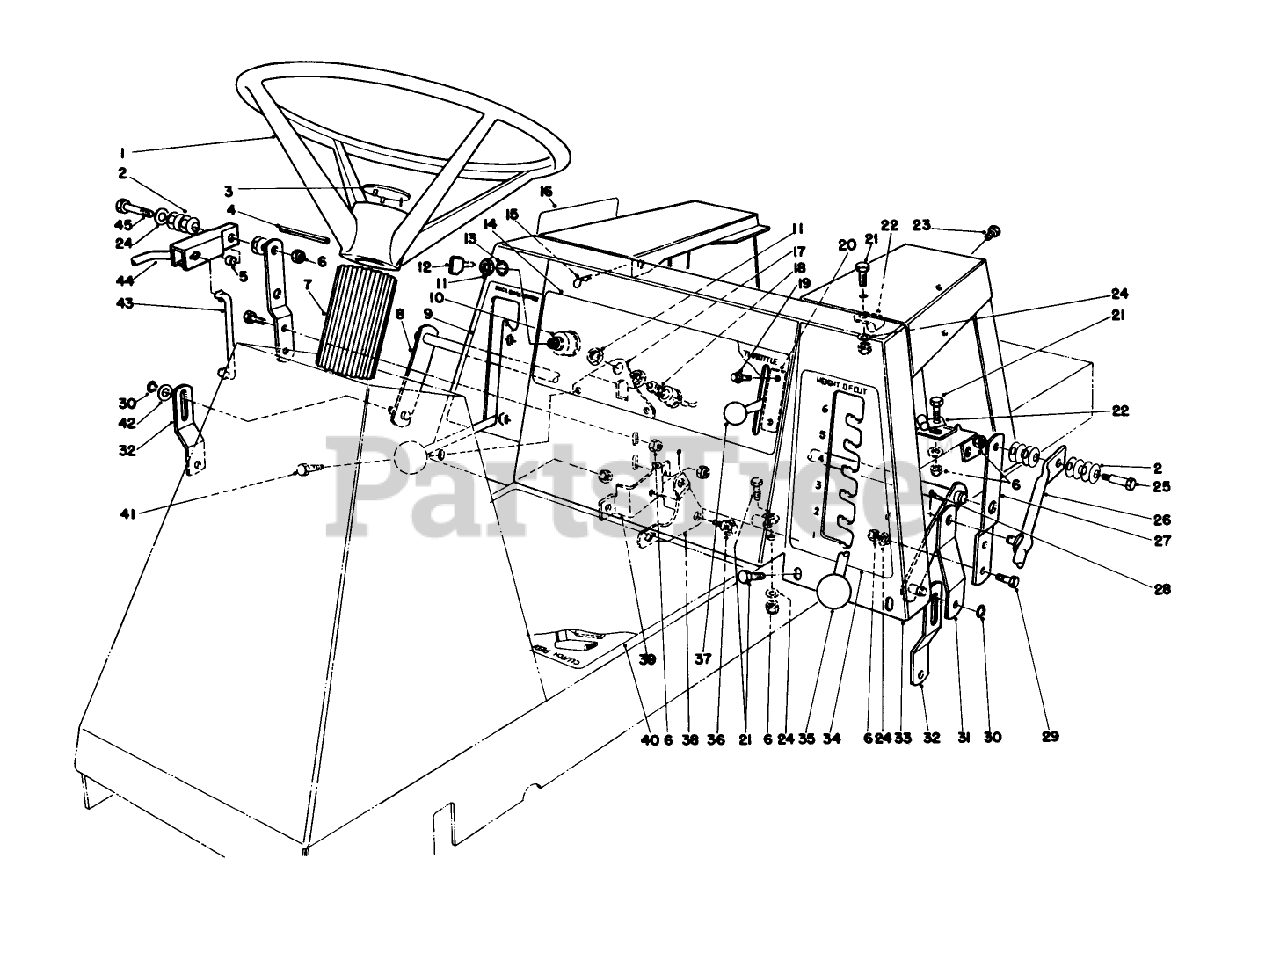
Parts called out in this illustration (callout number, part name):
1	STEERING WHEEL ASM
2	WASHER-BELLEVILLE
3	INSERT-STEERING WHEEL, TORO
4	PIN-ROLL
5	SPACER
6	NUT-LOCK, NI
7	COVER-STEERING SHAFT
11	NUT-HH
12	DECAL-HOC, LH
13	WASHER-LOCK
17	SWITCH MT BRKT
18	DECK SWITCH
19	SCREW-HWHTF
20	THROTTLE CONTROL
21	SCREW-HH
22	CLAMP
23	SCREW-HH
24	WASHER-PLAIN
25	BOLT-SHOULDER
26	HOC LEVER WA *B
28	PIN-COTTER
29	SCREW-HH
30	RING-RETAINING
34	HOC DECAL
36	SCREW-SHOULDER
38	DECK ENGAGE BELLCRANK
41	SCREW-HH
42	WASHER-FLAT
43	BELLCRANK LINK(PLTD)
44	SHIFT LEVER WA *B
45	SCREW-HH
